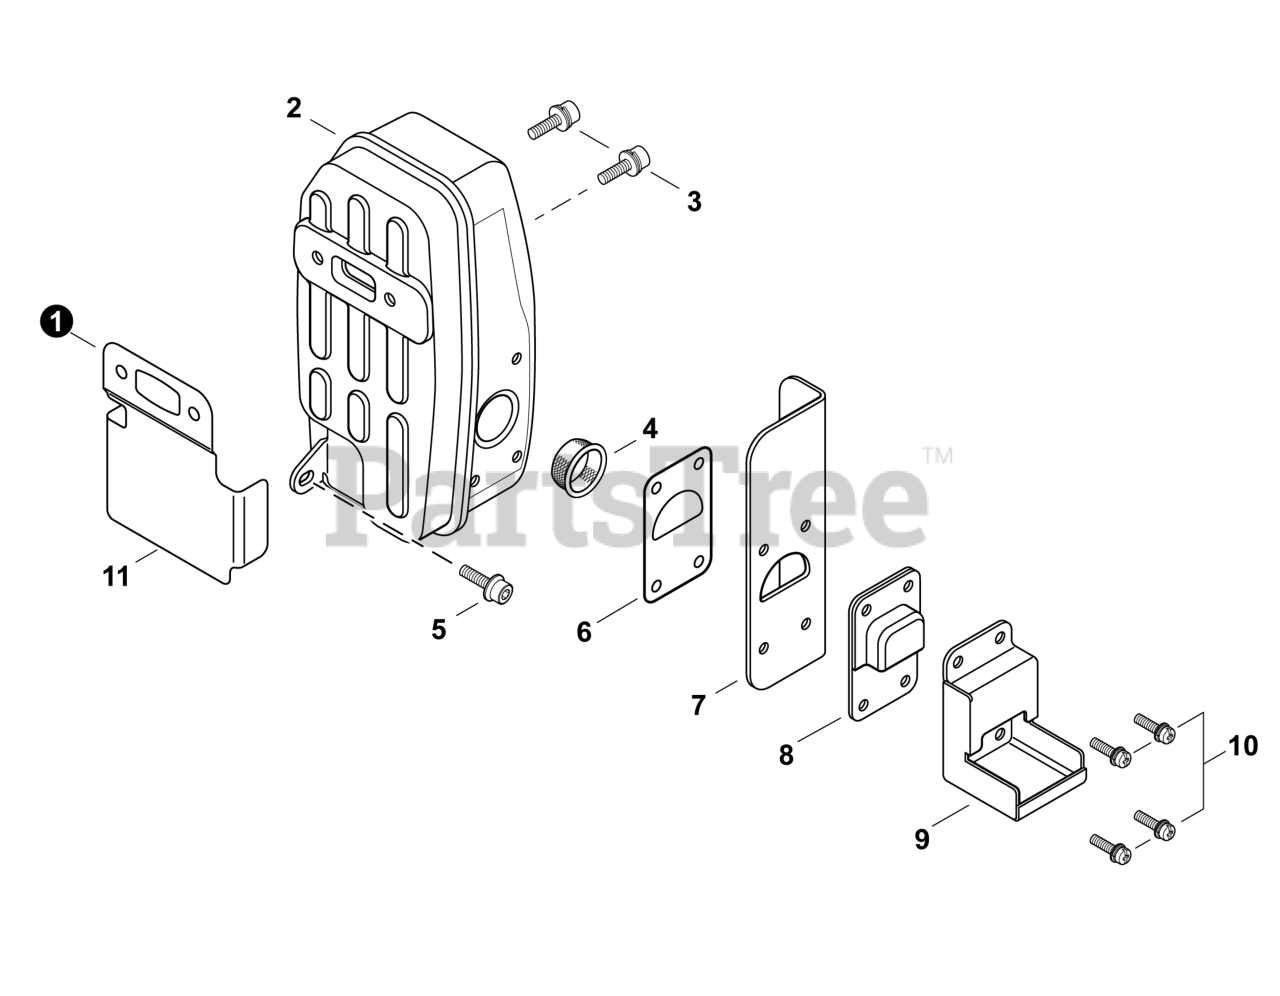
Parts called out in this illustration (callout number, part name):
1	HEAT SHIELD, EXHAUST
2	MUFFLER
3	BOLT, FLANGE 6×20
4	SCREEN, SPARK ARRESTER
5	BOLT 5×14
6	GASKET, EXHAUST
7	HEAT SHIELD, EXHAUST
8	GUIDE, EXHAUST
9	GUIDE, EXHAUST
10	SCREW 4×14
11	GASKET KIT
